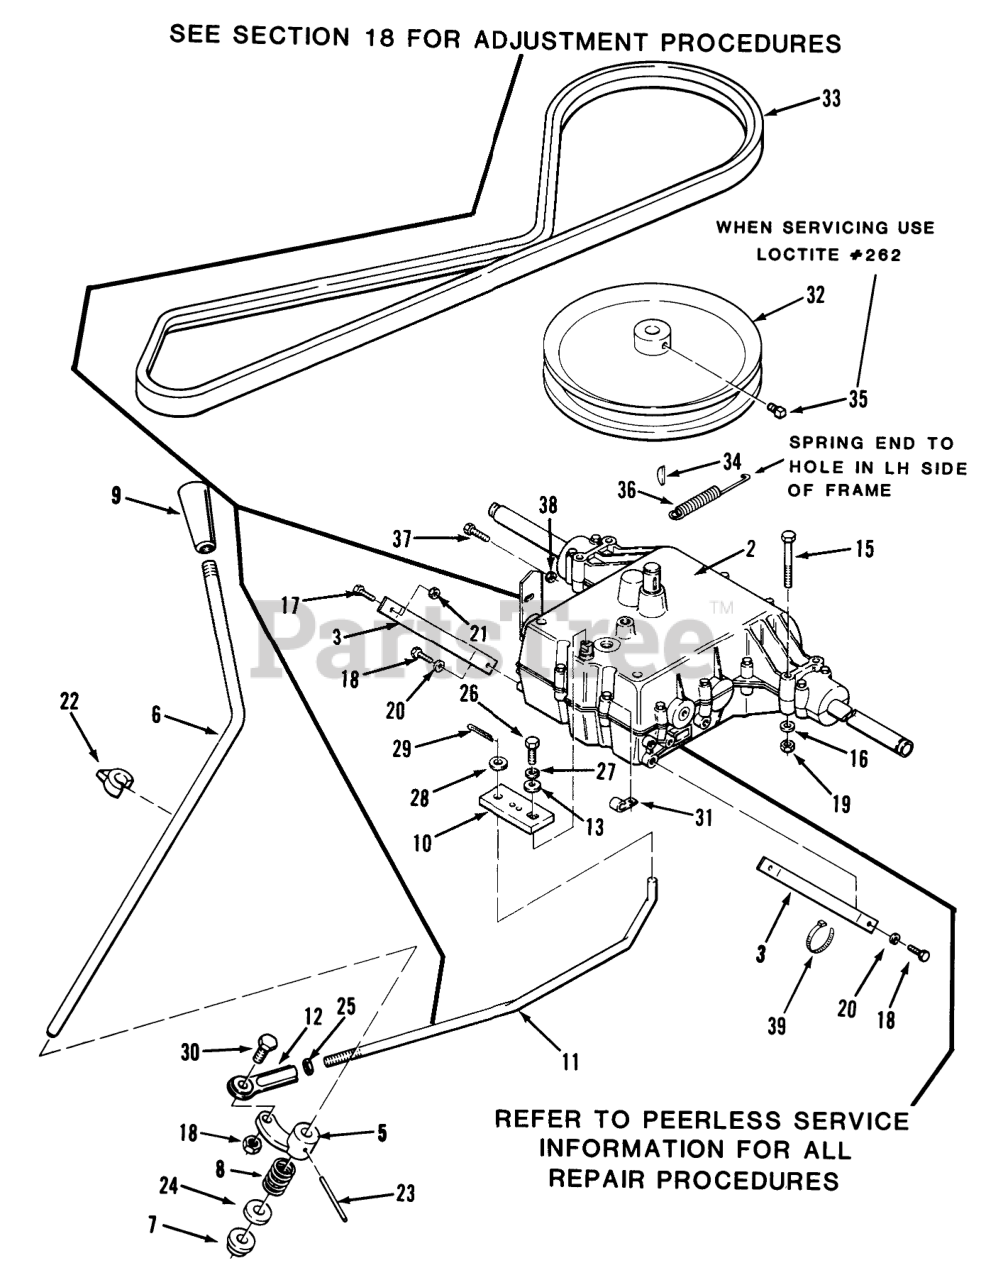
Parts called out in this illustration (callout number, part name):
2	Trans.-5-Spd.(Peerless Model 920-009)
3	TORQUE-STRAP R
5	ARM SHIFTER B
6	ROD-SHIFT LEVER
7	BUSHING-NYLINER
8	SPRING COMPRESSION
10	ARM-TRANSMISSION 5SP
11	ROD-LINKAGE
12	END-ROD
13	WASHER
15	SCREW-HH
16	WASHER-PLAIN
17	CARRIAGE BOLT -4
18	Screw
19	NUT-LOCK, NI
20	WASHER-LOCK
21	Nut
22	POINTER
23	SPIROL PIN 7/32X21/2
24	SHIM-WASHER
25	NUT-JAM
26	SCREW-HH
27	WASHER-LOCK
28	WASHER 5/16 SAE
29	PIN-COTTER
30	SCREW-HH
31	J-CLIP
32	PULLEY-TRANS
33	BELT-V
34	KEY-HI-PRO
35	SCREW-SQH
36	SPRING-EXTENSION
37	SCREW-HH
38	Nut
39	PLASTIC TIE
